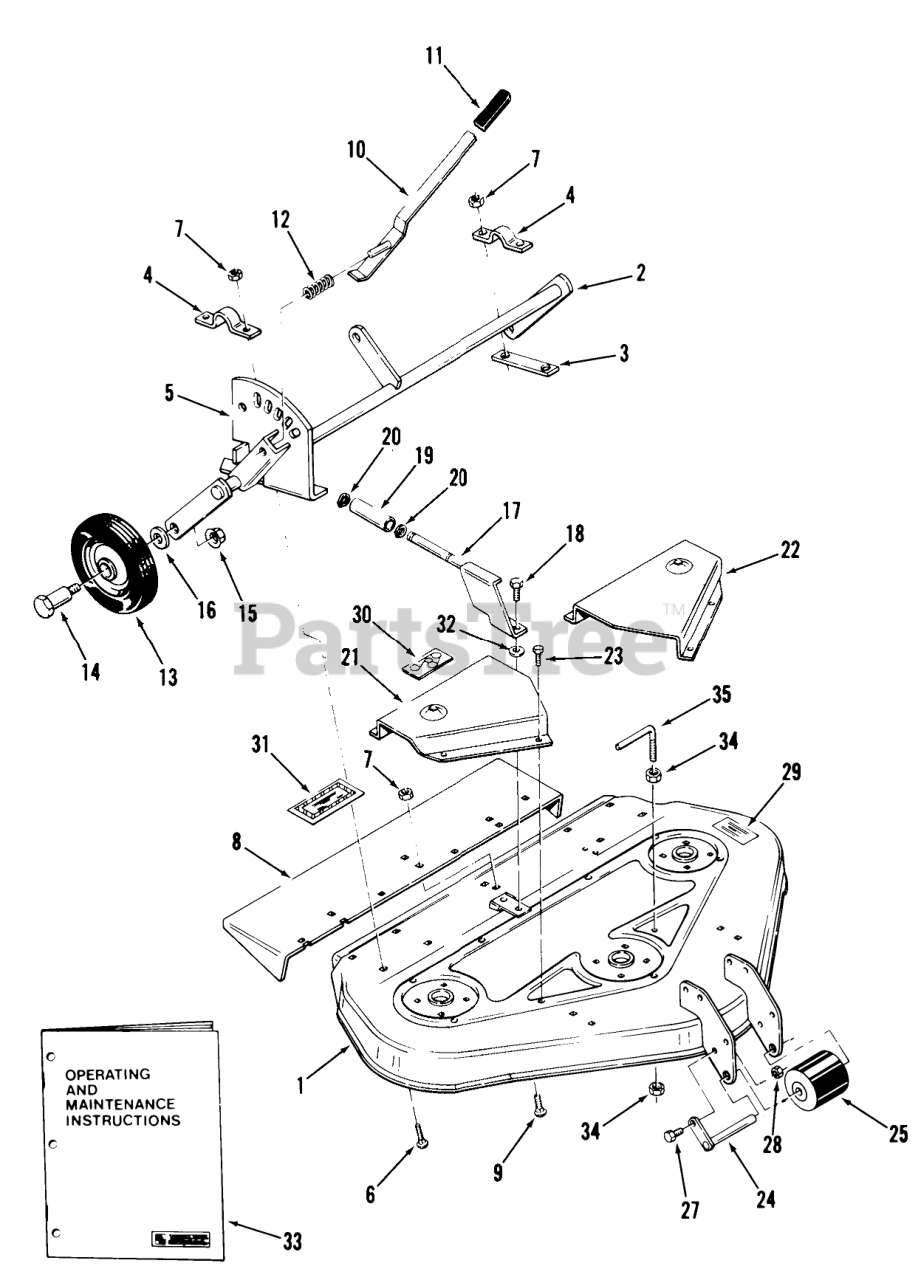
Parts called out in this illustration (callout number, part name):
1	ASSY-MOWER DECK 3 R
2	Gage Wheel Support
3	Strap
4	CLAMP
5	QUADRANT R (NS)
6	Bolt
7	Nut
8	Chute Extension
9	Bolt-Carriage
10	Lever
12	SPRING-COMPRESSION
13	Wheel 6 X 1.25
15	Nut
16	SHIM-WASHER
17	Rear Guide
18	Bolt
19	SPACER
20	Snap Ring
21	Belt Cover RH
22	Cover-Belt
23	Bolt
24	Roller Shaft
25	Roller
27	H H C S
28	Nut
29	Caution Decal
30	Decal-Height & Belt Adjustment
31	Decal-Caution
32	WASHER
33	Owner-s Manual (Mower)
34	Nut
35	BELT GUIDE
